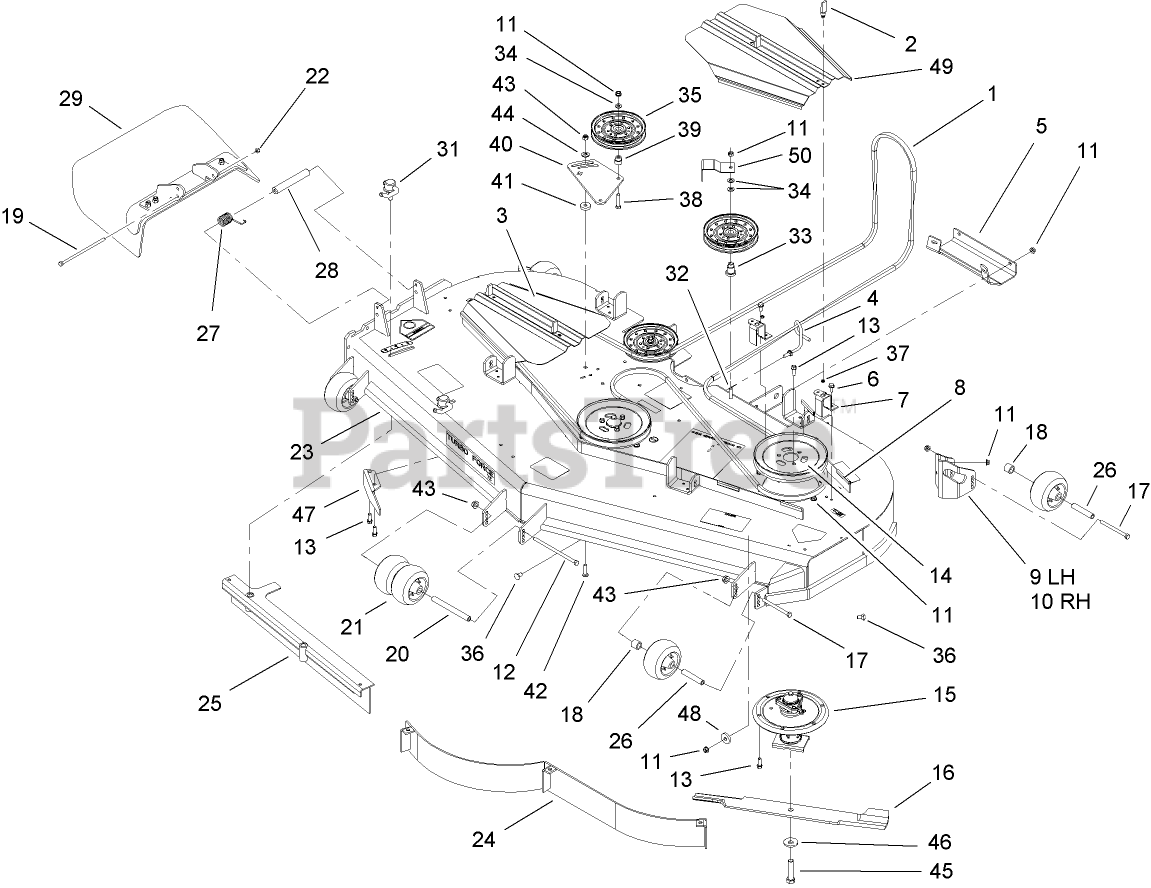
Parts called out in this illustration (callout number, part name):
2	LATCH-SWELL
3	COVER-BELT
4	GUIDE-BELT
5	Plate-Skid
6	SCREW-HWHTF
7	BRACKET-COVER
8	STRIP-SEAL
9	MOUNT-WHEEL, LH
10	MOUNT-WHEEL, RH
11	NUT-HHF, WHIZ
12	SCREW-HH
13	SCREW-HWH
14	Pulley
15	Spindle ASM
16	BLADE-HI FLOW, 24.5 INCH
17	SCREW-HH
18	TUBE-SPACER
19	SCREW-HH
20	SPACER-WHEEL
21	ROLLER-SCALP, ANTI
22	NUT-LOCK, NI
23	Deck Decal ASM
26	TUBE-SPANNER
27	SPRING-TORSION
28	SPACER
29	RUBBER DEFLECTOR ASM
31	LEVER ASM
32	SCREW-HH
33	MOUNT-PULLEY
34	WASHER-FLAT
35	Idler-Flat
36	SCREW-CARR
37	WASHER
38	SCREW-HH
39	BUSHING-IDLER
40	Plate-Idler
41	Spacer
42	SCREW-CARR
43	NUT-LOCK, NI
44	WASHER-BELLEVILLE
45	Screw-Cap
46	Washer-Blade Bolt, Heavy
47	BAFFLE-DISCHARGE
48	WASHER
49	COVER-BELT
50	GUIDE-BELT
99	BLADE-MID FLOW, 24.5IN
